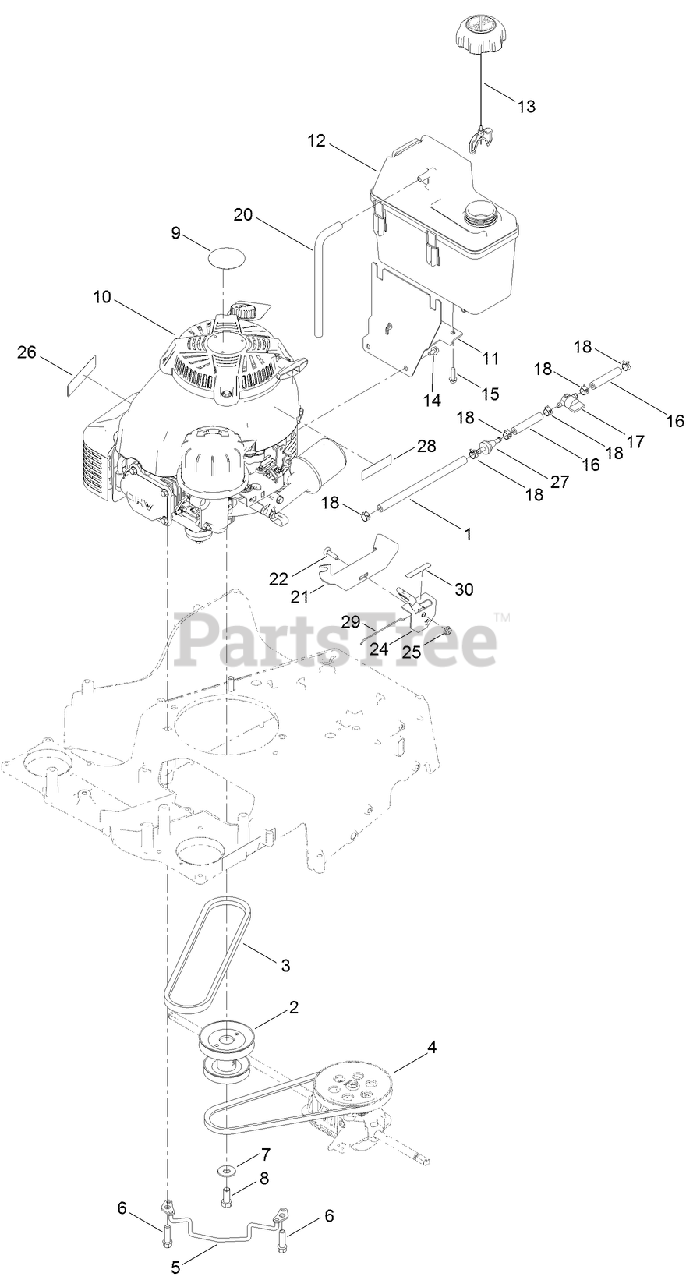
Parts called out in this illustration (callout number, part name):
1	HOSE-FUEL
2	PULLEY-ENGINE
3	V-BELT
5	GUIDE-BELT
6	SCREW-TAPTITE
7	WASHER-BELLEVILLE
8	SCREW-HH
11	MOUNT-TANK
12	TANK-FUEL
13	CAP-FUEL
14	SCREW-HWH
15	SCREW-HWH
16	HOSE-FUEL
17	VALVE-FUEL
18	CLAMP-HOSE
20	HOSE-VENT, CANISTER
21	BRACKET-MOUNT, THROTTLE
22	SCREW-CARR
24	CONTROL-THROTTLE
25	NUT-HF
26	DECAL-ARRESTOR, SPARK
27	FILTER-FUEL
28	DECAL-WARNING, ENGINE
29	WIRE-CONTROL
30	DECAL-THROTTLE, CHOKE
